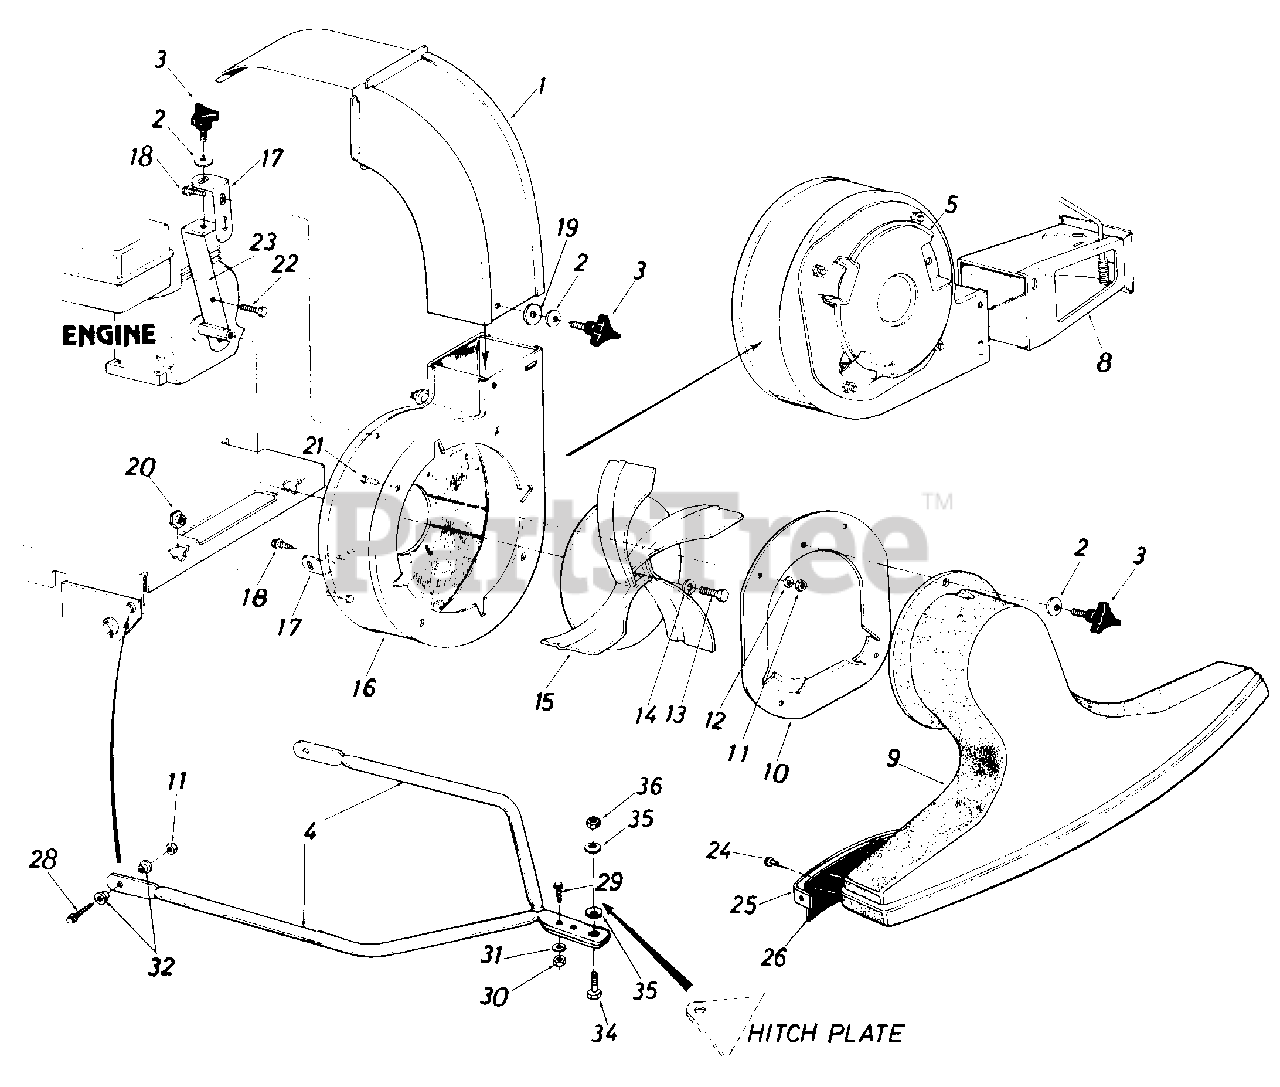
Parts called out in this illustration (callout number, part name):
3	3-Arm Thumb Scr. 5/16-18 x .75" Lg.
10	Nozzle Plate Ass'y.
11	Hex Nut 5/16-18 Thd.
12	L.-Wash. 5/16" I.D.
13	Hex Bolt 3/8-24 x 1.25" Lg.
14	L.-Wash. 3/8" I.D. H.D.
15	Air Vane Plate Ass'y.
16	Blower Housing Complete
19	Fl.-Wash. 5/16" I.D.
20	Hex Shoulder Nut .50 I.D.
21	Carriage Bolt 5/16 18 x .62" Lg.
22	Hex Locking Bolt 5/16-24 x .75" Lg.
28	Hex Bolt 5/16 18 x 1.00" Lg.*
29	Truss Mach. Scr. 1/4-20 x .75" Lg.
30	Hex Nut 1/4-20 Thd.
31	L.-Wash. 1/4" I.D.
32	Shoulder Spacer
34	Shld. Bolt .496 Dia.
35	Belleville Wash. .39 I.D. x 1.12 O.D.
36	Hex Jam L-Nut 3/8-16 Thd.
